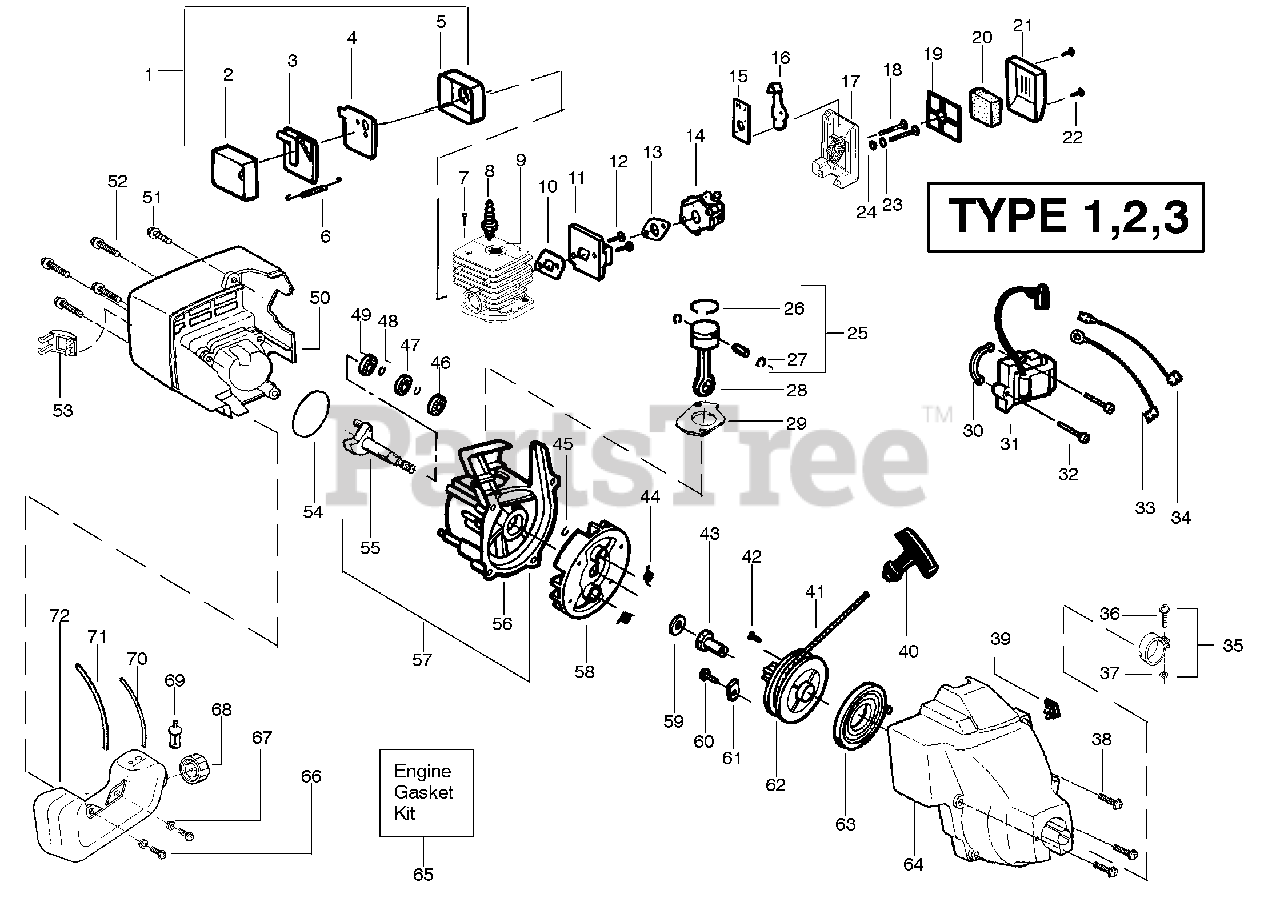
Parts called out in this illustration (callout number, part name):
1	Kit - Muffler S.A.
2	Muffler Cover
3	Muffler Baffle
4	Muffle Baffle-First
5	Muffler Body
6	Muffler Spring
7	Screw-Cylinder
8	Spark Plug (RCJ 8Y)
9	Kit - Cylinder
10	Gasket-Cyl./Carb.(kit)
11	Carb. Adaptor Type 1
11	Carb. Adaptor Type 2
13	Gasket-Carb.(kit)
14	Kit - Carburetor Ass'y (Wa-226)
14	Kit - Carburetor Ass'y (C1U-W7)
15	Choke Plate Mounting
16	Choke Shutter
19	Plate - Filter Support
20	Air Filter Foam
21	Air Filter Cover
23	Spacer-Choke
25	Kit - Piston
26	Piston Ring
27	Piston Pin Retainer
28	Connecting Rod Ass'y.
29	Gasket-Cylinder(kit)
30	Spacer-Module
31	Ignition Module
33	Assy-Ground Wire
34	Assy-Leadwire
35	Nose Cone Clamp Ass'y.
36	Screw-Nose Cone
37	Nut-Nose Cone
38	Screw
39	Kit-On/Off Switch
40	Starter Handle
41	Kit - Rope
43	Drive Coupling
44	Starter Dog Spring
45	Retain. Ring-C'shaft
46	Outer Bearing
47	Seal-C'case
48	Ring-C'case Ret.
49	Inner Bearing
50	Assy.-Fan Hsg/Shroud
52	Screw
53	Guard-Muffler
54	O-Ring-C'case(kit)
55	Assy-Crankshaft
56	Crankcase Ass'y.
57	C'case & C'shaft Assy.
58	Flywheel Ass'y.
59	Washer-Flat
61	Retainer-Can
62	Starter Pulley Kit
63	Starter Spring
64	Kit-Fan Hsg/Shroud
65	Kit-Engine Gasket
68	Assy-Fuel Cap
69	Assy-Fuel Pickup
70	Kit-Fuel Line (Small)
71	Kit-Fuel Line (Large)
72	Assy-Fuel Tank
